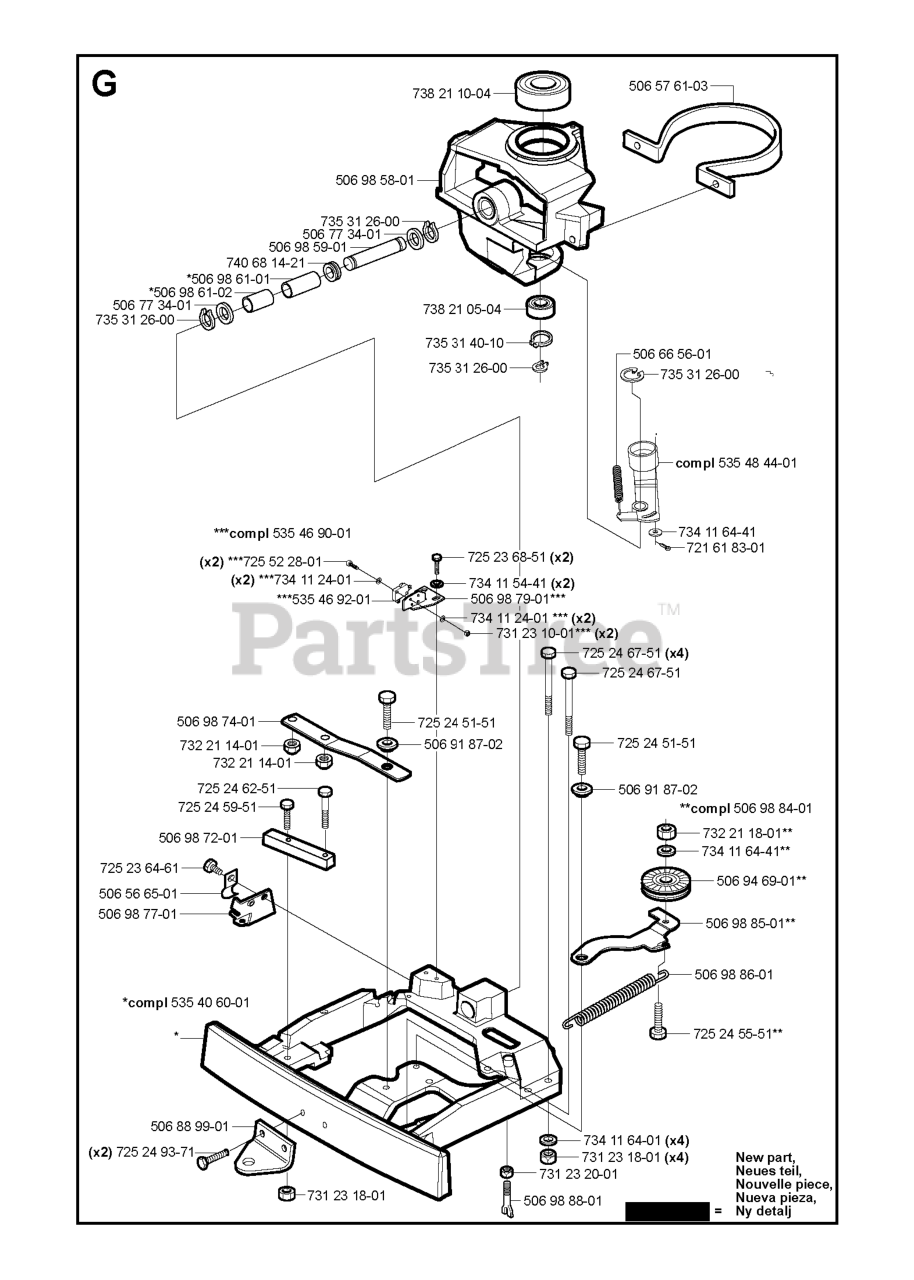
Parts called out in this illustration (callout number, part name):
2	KEY, 1/4 SQ X 1 1/4
7	HUB.PNT.GT.PM.1IN.AXLE.E-DIP
15	WASHER PLAIN WASHER 3/8 X 0.08
17	SPRING.BRAKE.K46.GREEN
26	SPRING.RETURN.CRUISE
29	ROD.BRAKE.K46
33	E RING HYT
35	ROD ROD.PARKINGBRAKE.GT.HUSQ/P
42	PEDAL COVER
50	IDLER.FLAT.910.OFFSET
51	NUT LOCK FLG 3/8-16 UNC
52	IDLER.V-GROOVE.910.OFFSET
64	SHAFT.ASM.PEDAL.BRK.CNTR
69	HAIRPIN.SOFT.ZINC.059X1.125
70	CONSOLE.ASM.RH.GT.FC.HUSQ
73	BOLT.HEX.FLNG.5/16-18X3.75
125	SCREW
153	RETAINER M
161	SPRING, RETURN LT
166	NUT.PUSH.625
167	LATCH.BRAKE.SPRING
170	KEEPER.CENTER SPAN.1.688
177	PIN COTTER;LOCKING;BOWTIE;1IN
183	SPACER.SPLIT.1.000IDX1.75
184	HANDLE.PARKING.BRAKE.H (BLK)
186	SPACER.RETAINER
188	LINK.CLUTCH.GROUND DRIVE.LONG
189	BELLCRANK.GROUND.DRIVE.TEX.
190	KEEPER.BELLCRANK.DRIVE
196	SCREW 3/8-16X1
206	BRACKET.MOUNT.CRUISE.LATCH
209	ROD ROD.CRUISECONTROL.GT.HUSQ/
211	BEARING.NYLON
213	KNOB.CONTROL.CRUSIE.HU
214	PEDAL.FORWARD.PAD.TEX
220	REFLECTOR.RH.TEX GT
221	RETAINER.SPRING.CLIP.H
222	WASHER 21/32 X 1-1/4 X 10 GA.
225	KEEPER.BELT.TRANSAXLE.K46
231	IDLER.V-GROOVE.1.688.OFFSET
381	Service Kit
